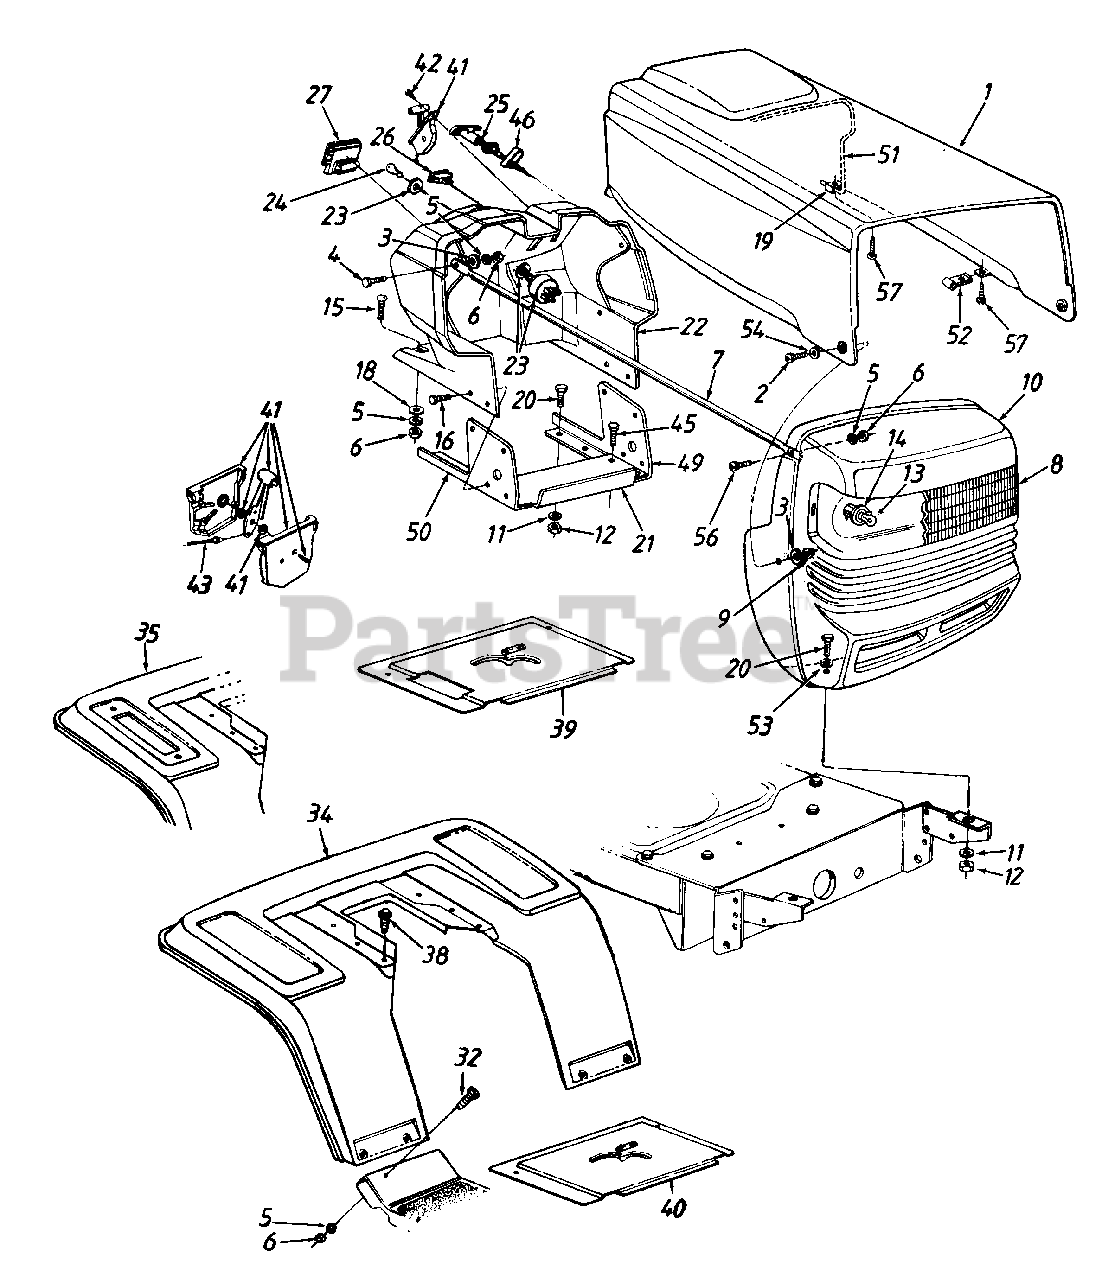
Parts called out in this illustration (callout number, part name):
3	Fl-Wash. .28" I.D. x .75" O.D.
4	Hex Bolt 1/4-20 x .88" Lg.
5	L-Wash. 1/4" I.D.
6	Hex Nut 1/4-20 Thd.
9	Flange L-Nut 1/4-28 Thd.
12	Hex Nut 5/16-18 Thd.
13	Lamp
14	Socket
15	Carriage Bolt 1/4-20 x .75" Lg.
16	Hex Wash. Hd. TT-Tap Scr. 1/4-20 x .5" Lg.
18	Bolt Retainer 1/4" I.D.
19	Speed Nut 1/4-20 Thd.
20	Hex Bolt 5/16-18 x .75" Lg.
23	Ignition Switch
24	Ignition Key
25	Choke Control
26	Light Switch
27	Ammeter
32	Truss Mach. Scr. 1/4-20 x .5" Lg.
41	Throttle Box Ass'y.
42	Truss Mach. AB-Tap Scr. #10 x .5" Lg.
43	Throttle Control Wire
45	Hex Wash. Hd. B-Tap Scr. 5/16-18 x .5" Lg.
46	Choke Retainer
52	Flat Fastener (Special)
53	Fl-Wash. .344" I.D. x 1" O.D.
54	Spr. Wash. .39" I.D. x .62" O.D.
55	Bell-Wash. .345" I.D. x .88" O.D.
56	Pan Hd. Scr. 1/4-20 x .75" Lg.
57	Truss Mach. Scr. #10-24 x .5" Lg.
